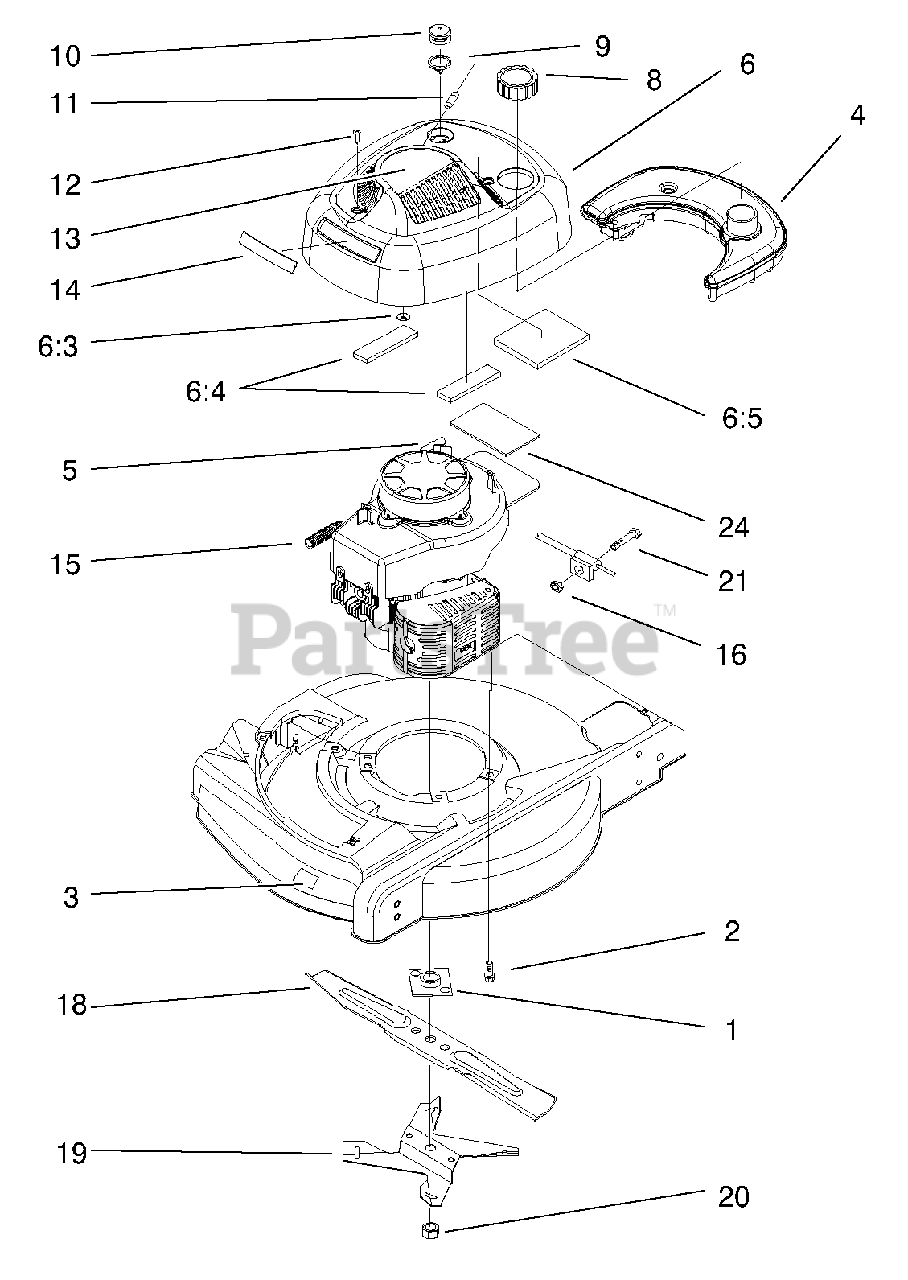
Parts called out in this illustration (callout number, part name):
1	PLATE & COLLAR ASM
2	SCREW-HH
3	DECAL-DECK
5	LINE-FUEL
6	SHROUD & RECOIL COVER ASM
6:3	NUT-PUSH
6:4	STRIP-FOAM
6:5	STRIP-FOAM
8	FUEL & OIL CAP ASM
9	BODY-PRIMER
10	BULB-PRIMER
11	STOP-ROPE
12	SCREW-SEMS, PAN
13	DECAL - RECOIL
14	APPLIQUE-SHROUD
15	SPRING-COMPRESSION
16	Nut
18	Blade
19	FAN-MULCHING
20	NUT-BLADE
24	PAD-FOAM S
